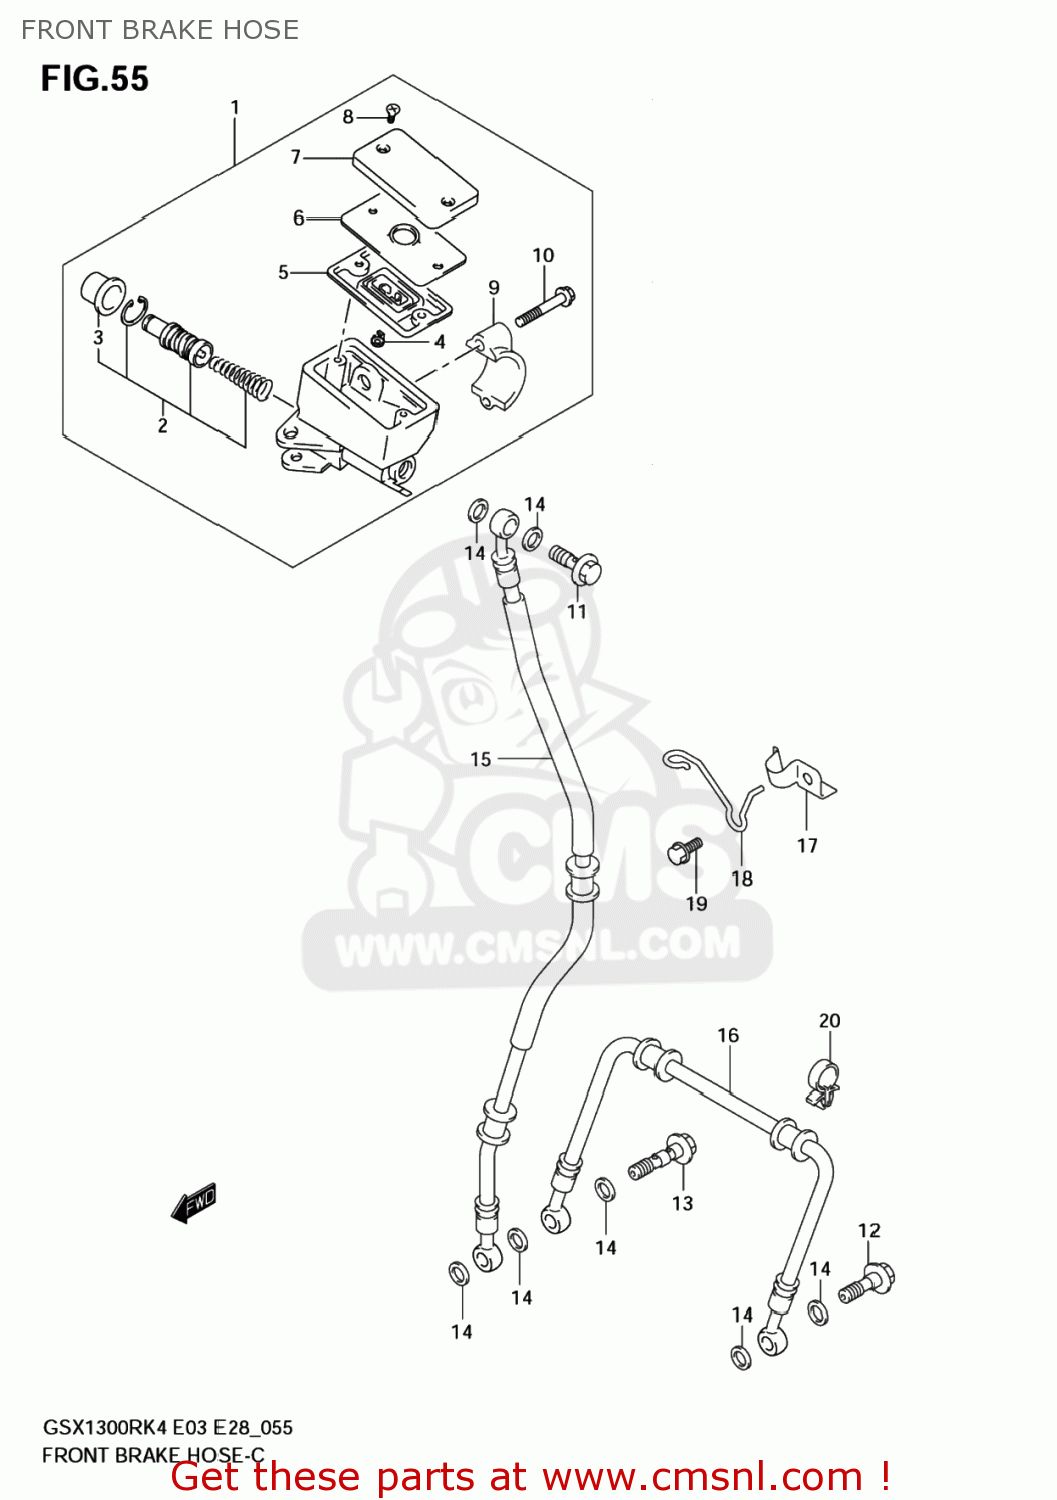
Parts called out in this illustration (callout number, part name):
1	CYLINDER ASSY,FR MASTER
2	PISTON & CUP SET
3	BOOT
4	PROTECTOR
5	6
6	PLATE,DIAPHRAGM
7	CAP
8	SCREW
9	HOLDER
10	BOLT(6X22)
11	BOLT UNION
12	BOLT UNION
13	BOLT UNION
14	WASHER(10X15X1.5)
15	HOSE,FRONT BRAKE NO.1
16	HOSE,FRONT BRAKE NO.2
17	CLAMP,FR BRAKE HOSE UPR
18	GUIDE,FR BRAKE HOSE NO.1
19	BOLT
20	CLAMP
